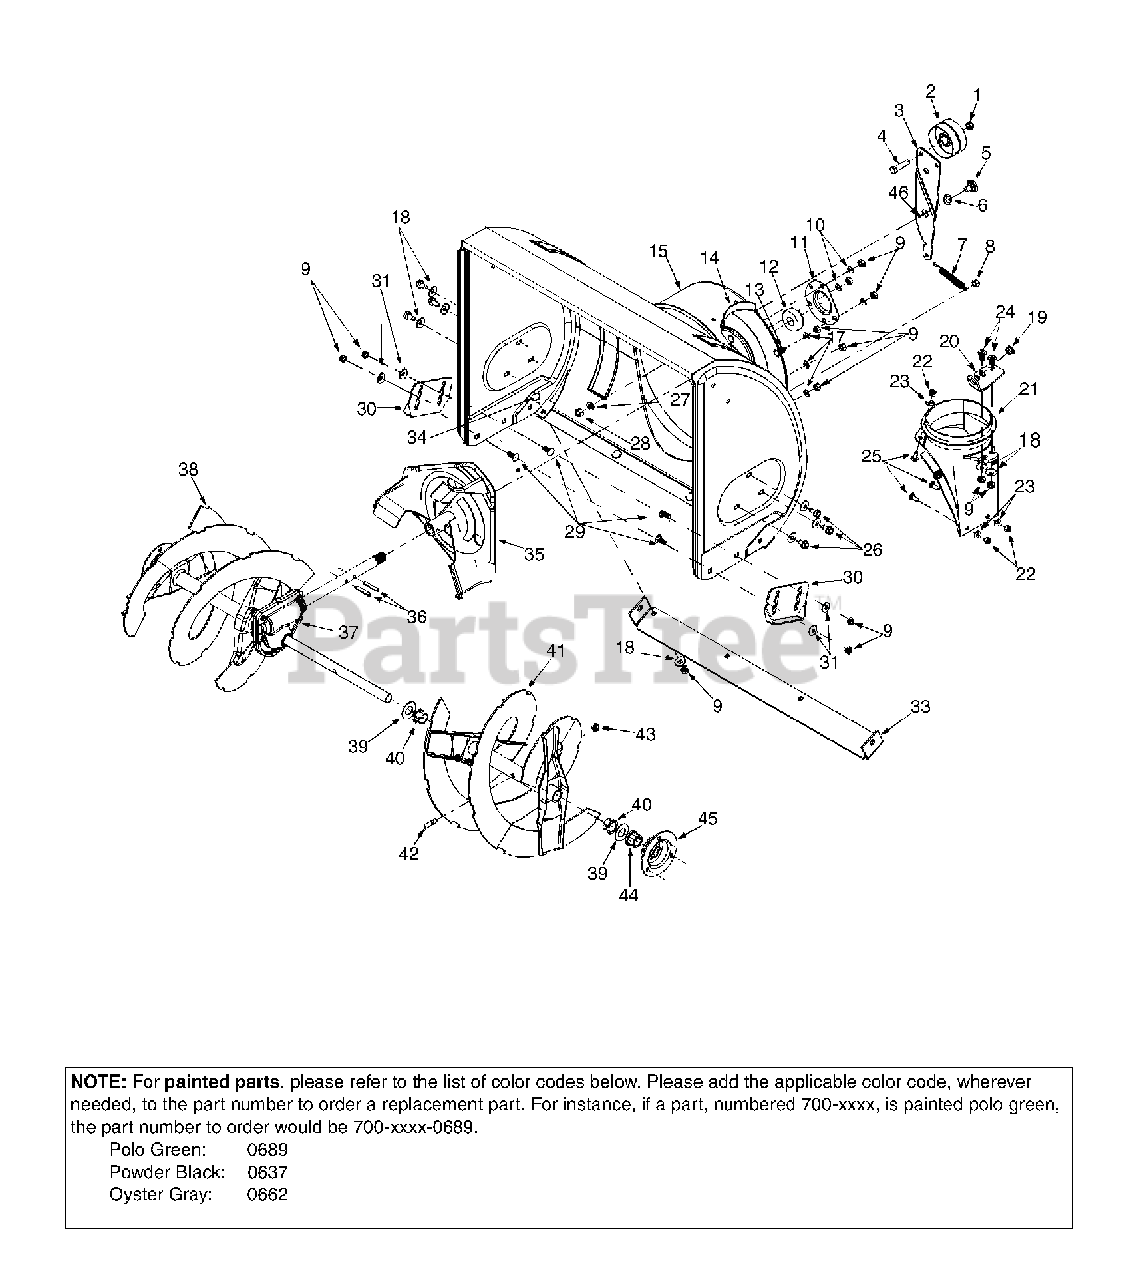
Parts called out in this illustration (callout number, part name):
1	Lock Jam Nut 3/8-24
2	Flat Idler
4	Hex Cap Screw 3/8-24 x 1.50
5	Shoulder Screw
6	Flat Washer
7	Extension Spring
8	Hex Nut 5/16-18
9	Hex Nut 5/16-18
10	Lock Washer 5/16
11	Bearing Housing
12	Ball Bearing
13	Carriage Bolt 5/16-18
18	Bell Washer
19	Bushing
21	Chute Adapter
22	Hex Lock Nut 1/4-20
23	Flat Washer
24	Carriage Bolt
25	Carriage Screw 1/4-20 x .75
26	Hex Washer Screw 5/16-18
27	Lock Washer 3/8
28	Hex Nut 3/8-16
29	Carriage Bolt 5/16-18 x .75
31	Bell Washer
34	Carriage Bolt 5/16-18 x .62
36	Roll Pin
37	Gear Assembly
40	Flange Bushing
42	Shear Bolt 5/16-18 x 1.5
43	Lock Nut 5/16-18
44	Hex Flange Bearing
46	Grease
